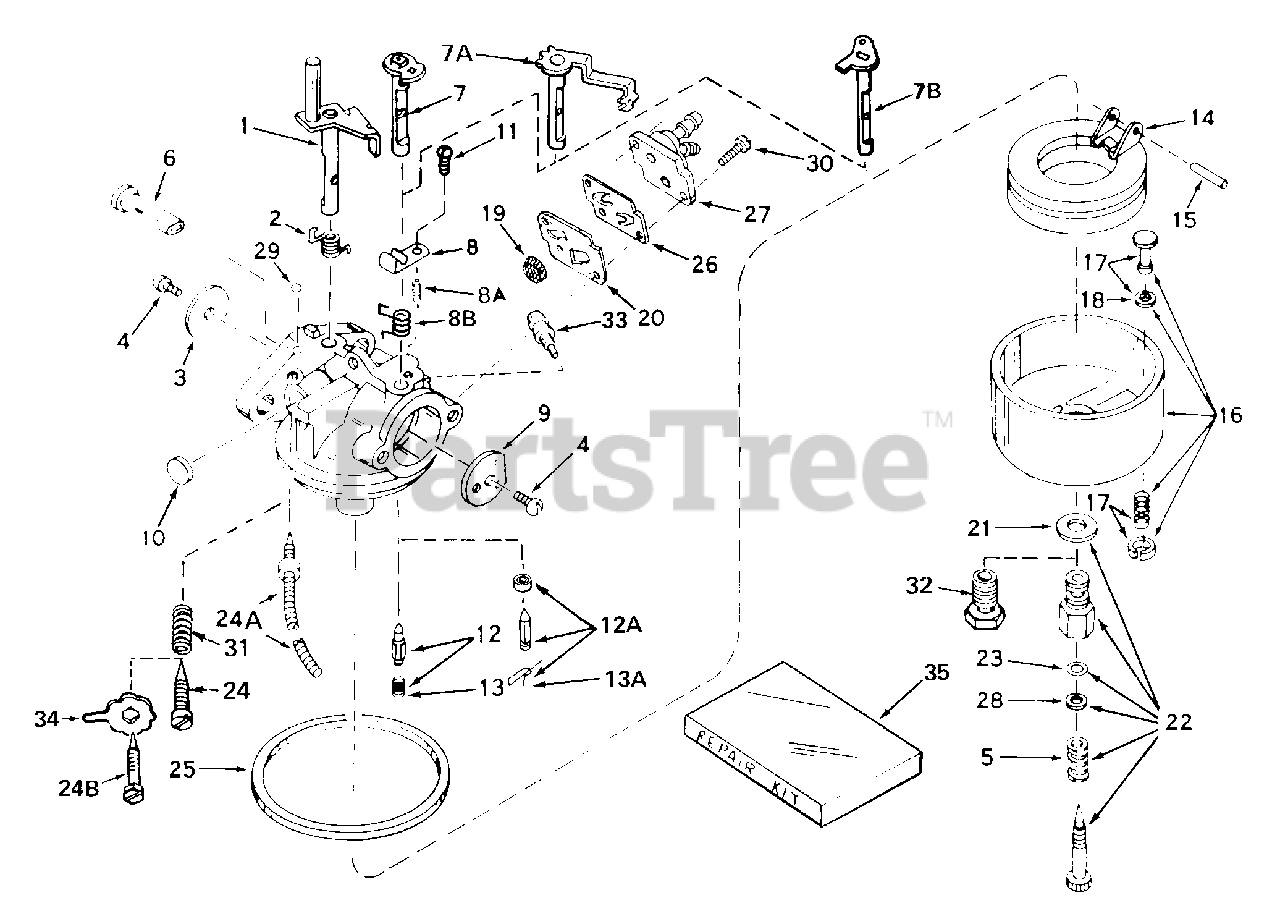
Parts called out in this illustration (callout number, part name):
1	"Shaft & Lever Assy., Throttle
2	Spring, Throttle return
3	Shutter, Throttle
4	Screw, Rd. hd. 4-40 x 3/16
7	Shaft & Lever Assy., Choke
8	Spring, Detent
9	Shutter, Choke
10	Plug, Welch
11	Screw, Rd. hd. 6-32 x 3/16
12A	Inlet Needle, Seat & Clip Assy.
13A	Clip, Inlet Needle
14	Float, Carburetor
15	Shaft, Float
16	Bowl, Float
21	Gasket, Bowl-to-body
24A	Screw Assy., Idle adjustment
25	Gasket, Bowl-to-body
29	Shot,Lead
32	Nut, Float Bowl
33	Fitting, Fuel inlet
